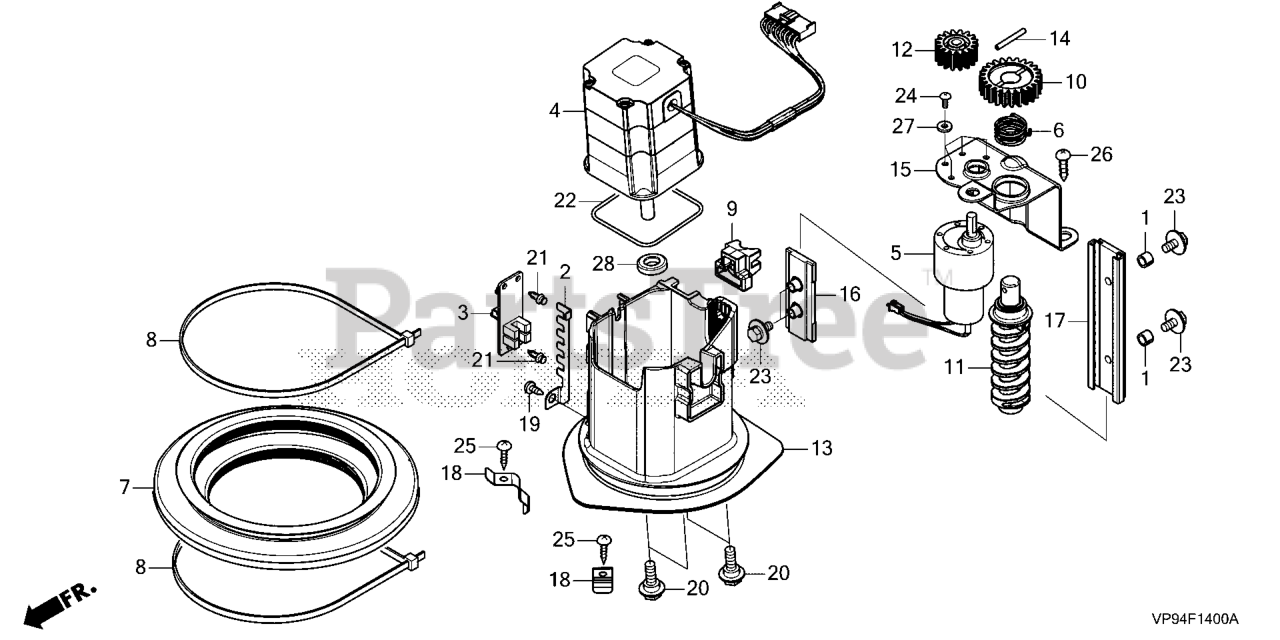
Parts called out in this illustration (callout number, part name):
1	COLLAR, CONTROL COVER
2	PLATE, HEIGHT SENSOR
3	SENSOR ASSY., HOUSING POSITION
4	MOTOR ASSY., WORK
5	MOTOR ASSY., HEIGHT ADJUST
6	SPRING, RATCHET RETURN
7	BOOT, MOTOR HOUSING
8	BAND, BOOT
9	GEAR, DRIVEN
10	GEAR, MOTOR DRIVEN
11	GEAR, DRIVE
12	GEAR, MOTOR DRIVE
13	HOUSING, MOTOR
14	SHAFT, HEIGHT ADJUST
15	BRACKET, HEIGHT ADJUST MOTOR
16	CARRIAGE, HEIGHT ADJUST
17	RAIL, HEIGHT ADJUST
18	PLATE, HOUSING TENSION
19	SCREW, TAPPING (4X8) (PO)
20	BOLT, SPECIAL (6MM)
21	RIVET, PUSH (3.5X7)
22	O-RING, MOTOR MOUNT
23	BOLT-WASHER (5X12)
24	SCREW, PAN (3X5)
25	SCREW, TAPPING (4X12)
26	SCREW, TAPPING (5X16) (PO)
27	WASHER, PLAIN (3MM)
28	OIL SEAL KIT
